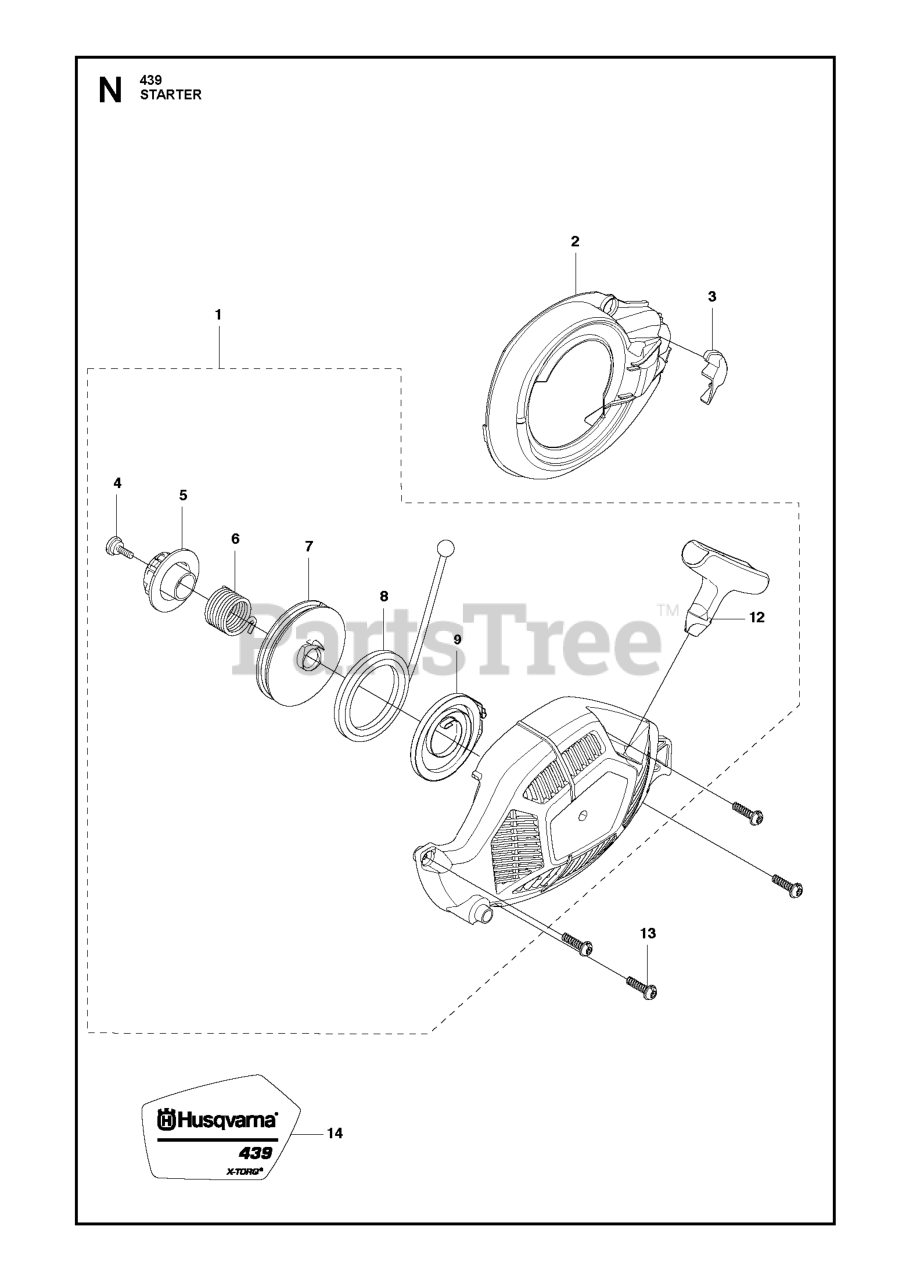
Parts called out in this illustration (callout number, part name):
1	STARTER ASSY 439
3	GUIDE, DF (GZ3500T)
5	CAM, PLATE
9	SPRING ASSY
14	DECAL STARTER 439
